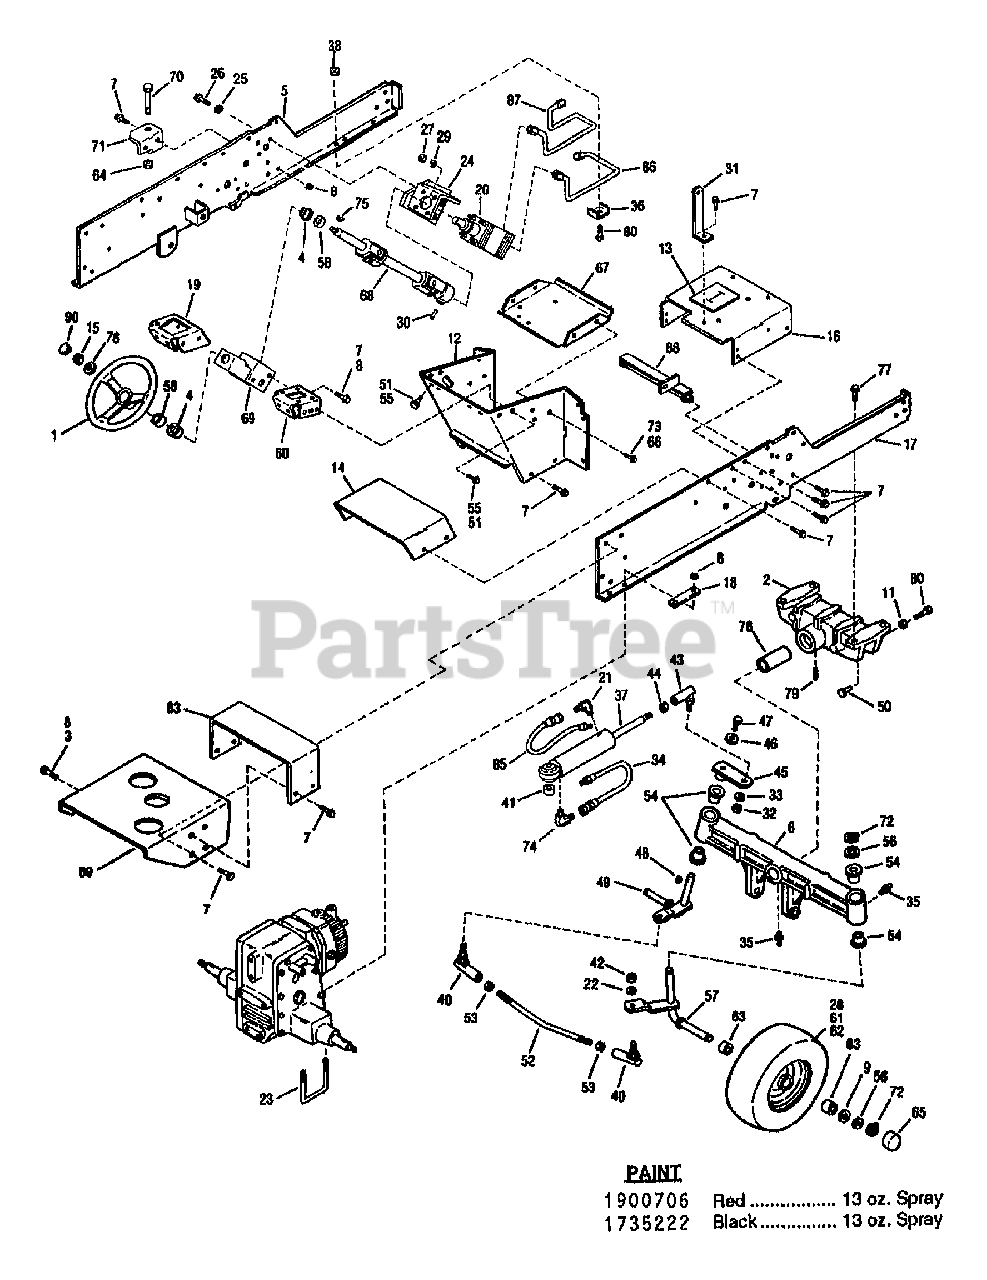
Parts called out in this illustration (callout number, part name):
1	WHEEL-STEERING
2	BOLSTER-FRONT AXLE
3	SCR-HFLK 3/8-16X1.00 ZP
4	BEARING-FLANGED NYLON
6	AXLE-FRONT
8	NUT-HFLK 3/8-16 ZP
9	SPACER-1.75X1.015X.179
11	NUT-HEX JAM 5/16-18
12	SUPPORT
14	TUNNEL W/DECAL
15	NUT-H/LK 3/8-16
16	SUPT-BATTERY/FUEL TANK
18	DOUBLER-FRAME REAR
19	STEERING BRACKET
20	KIT-STEERING VALVE
21	ELBOW
22	WASHER-LK .5
23	BOLT-U
24	SUPT-STEERING PUMP
25	WASHER-LK .438 ZP
26	SCR-HH 1/2-14X1.00
27	NUT-HEX 5/16-24
28	STEM-VALVE
29	WASHER-LK .312 ZP
30	PIN-ROLL 1/4 X 1-1/4
31	BRACE-STEERING
32	NUT-HEX 5/8-18
33	WASHER-LK 1.072X.634X.156
34	ASSM-HOSE
35	FITTING-GREASE 1/4-28X2.00
36	CLAMP
37	CYLINDER-HYDRAULIC
38	NUT-TOP/LK 5/16-18 ZP
40	JOINT-BALL
41	SLEEVE-CYLINDER
42	NUT-H/LK 1/2-20 ZP
43	JOINT-BALL
44	NUT-HEX/JAM 5/8-18 ZP
45	ARM-STEERING
46	WASHER-1.75X.328X.1345
47	SCR-HFLK 5/16-18X.75 ZP
48	KEY-WOODRUFF .25X.875
49	SPINDLE-WHEEL LEFT
50	PIN-WELD
51	SCR-TRUSS HD 5/16-18X.62
52	ROD-TIE
53	NUT-JAM
54	BEARING-FLANGE
55	NUT-HFLK 5/16-18 ZP
56	WASHER-THRUST
57	SPINDLE-WHEEL RH
58	COLLAR
60	BRKT-STEERING
61	WHEEL
62	TIRE-16X6.50-8
63	BEARING-BALL
64	NUT-LOCK
66	SCR-HFLK 1/4-20X.50 ZP
67	CARRIER-BATTERY
68	ASSM-STEERING SHAFT
69	ASSM-SUPPORT
70	SCR-HH 5/8-11X3.0 G5
71	BRKT-CYLINDER
72	RING-HEAVY EXT HD 1.0 ID
73	NUT-HF/LK 1/4-20 ZP
74	ELBOW
75	KEY-WOODRUFF .188X.75
76	WASHER-FLAT 3/8 SAE
77	SCR-HFLK 3/8-16X1.00 ZP
79	PIN-.312X.75
80	SCR-HH 5/16-18X1.0 G5 ZP
83	SUPPORT-FENDER
85	ASSM-HOSE
86	ASSM-TUBE
87	ASSM-TUBE
88	SUPPORT-FRAME
